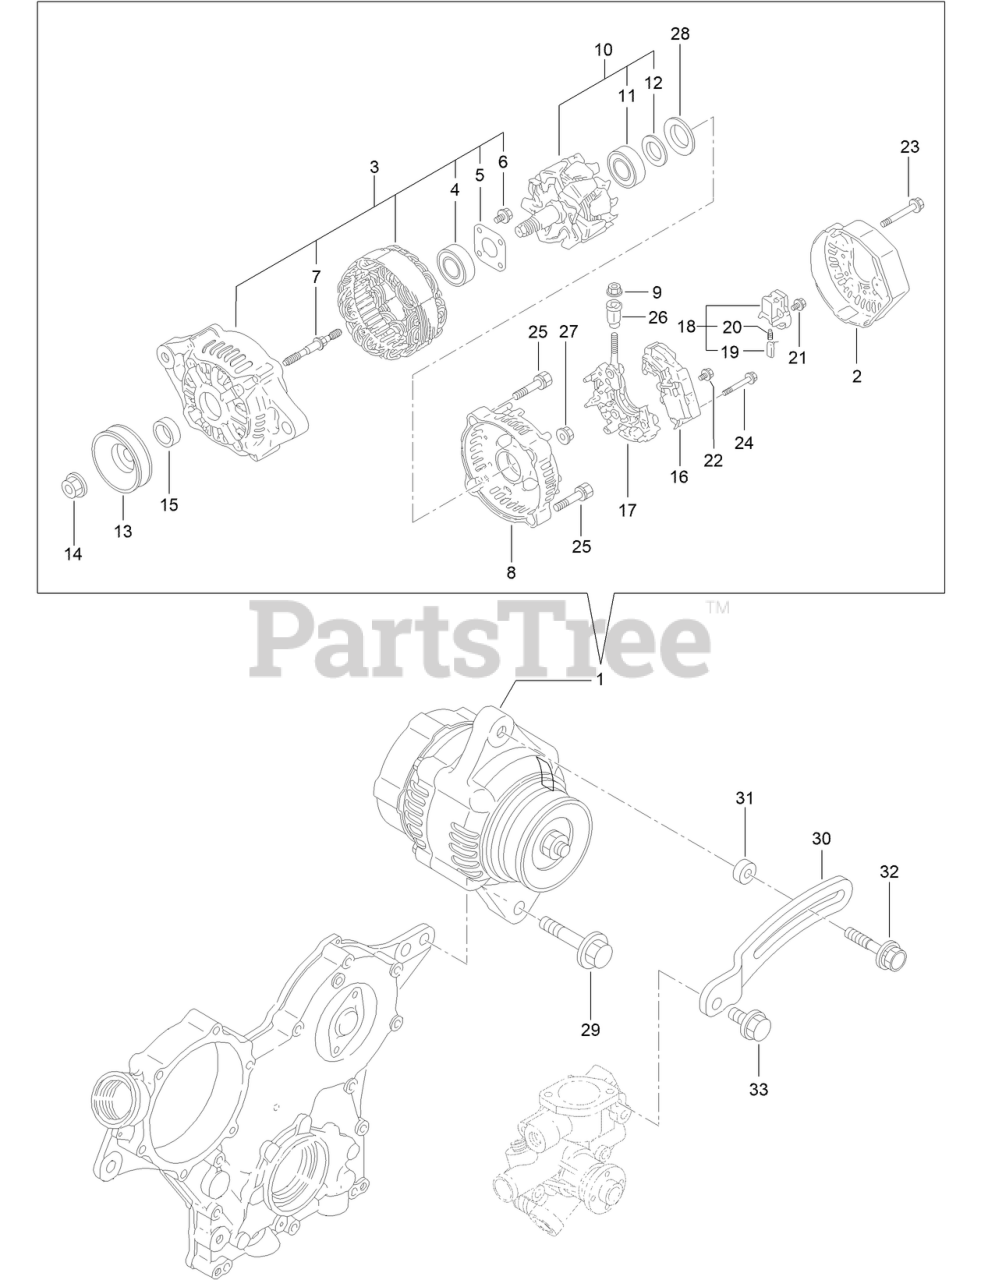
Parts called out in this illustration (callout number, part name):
1	ALTERNATOR (12V-40A)
3	FRAME ASM
4	BEARING-BALL
5	PLATE-RETAINER
8	REAR FRAME ASM
10	ROTOR ASM
11	BEARING-BALL
13	PULLEY
15	COLLAR
16	REGULATOR ASSY
17	HOLDER
18	HOLDER
19	BRUSH ASM
20	SPRING
26	BUSHING-INSULATION
28	WASHER
30	SPACER
31	SPACER-ADJUSTER
